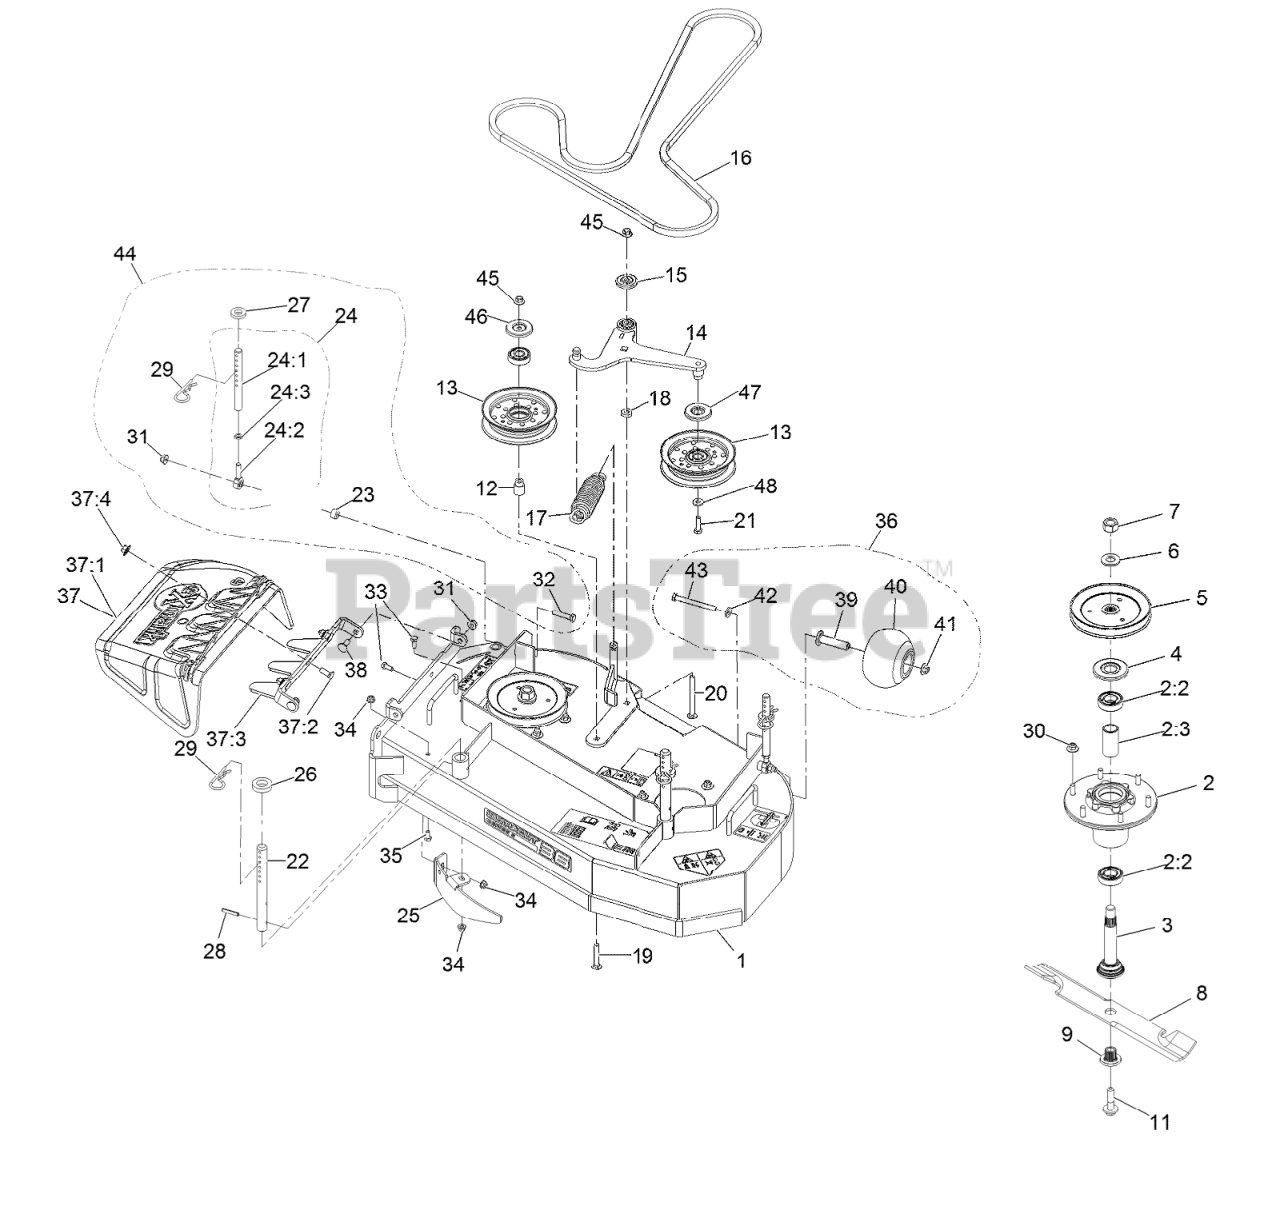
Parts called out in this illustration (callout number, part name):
1	ASM, DECK W/ DECALS, 36"
2	ASM-CUTTER HSG WITH BEARINGS
2:2	BEARING-BALL
2:3	SPACER-BEARING
3	ASM-SPINDLE AND SEAL
4	GUARD,BEARING TOP .989
5	SHEAVE,BLADE DRIVE 6.50
7	NUT-HEX
9	BUSHING,SPLINED
11	SCREW,SEMS 1/2-20 X 2.19
12	BUSHING-IDLER
13	IDLER-PULLEY, FLAT
14	ASM-ARM, IDLER
15	GUARD-TOP
16	BELT-5V
17	SPRING-EXTENSION
18	SPACER
19	Bolt-Carriage 3/8-16 X 2 1/4
20	SCREW-CARR
21	SCREW-HH
22	Rod, Deck Support
24:1	LINK,SUPPORT
24:2	BALLJOINT
24:3	NUT-HJ
25	BAFFLE, DOGLEG
26	SPACER-DECK SUPPORT
29	PIN,HAIR COTTER
30	Nut-Nyloc 3/8-16 Flg
31	NUT-HF, NI
32	SCREW-HH
33	SCREW-HH
34	NUT-HF, NI
35	SCREW-HH
36	KIT, ANTI-SCALP ROLLER
37	ASM, DISCHARGE CHUTE
37:1	CHUTE,DISCHARGE
37:2	BRACKET, DISCHARGE CHUTE
37:3	SCREW-CARR
37:4	Nut-Nyloc 3/8-16 Flg
38	SCREW-CARR
39	AXLE, ROLLER
40	ROLLER-SCALP, ANTI
41	Nut-Nyloc 3/8-16 Flg
42	WASHER-BELLEVILLE
43	SCREW-HH 3/8-16 X 3 3/4 GR 8
44	KIT,SUPPORT LINK W/PIN
46	SHIELD-DUST
47	SHIELD-GUARD, DUST
